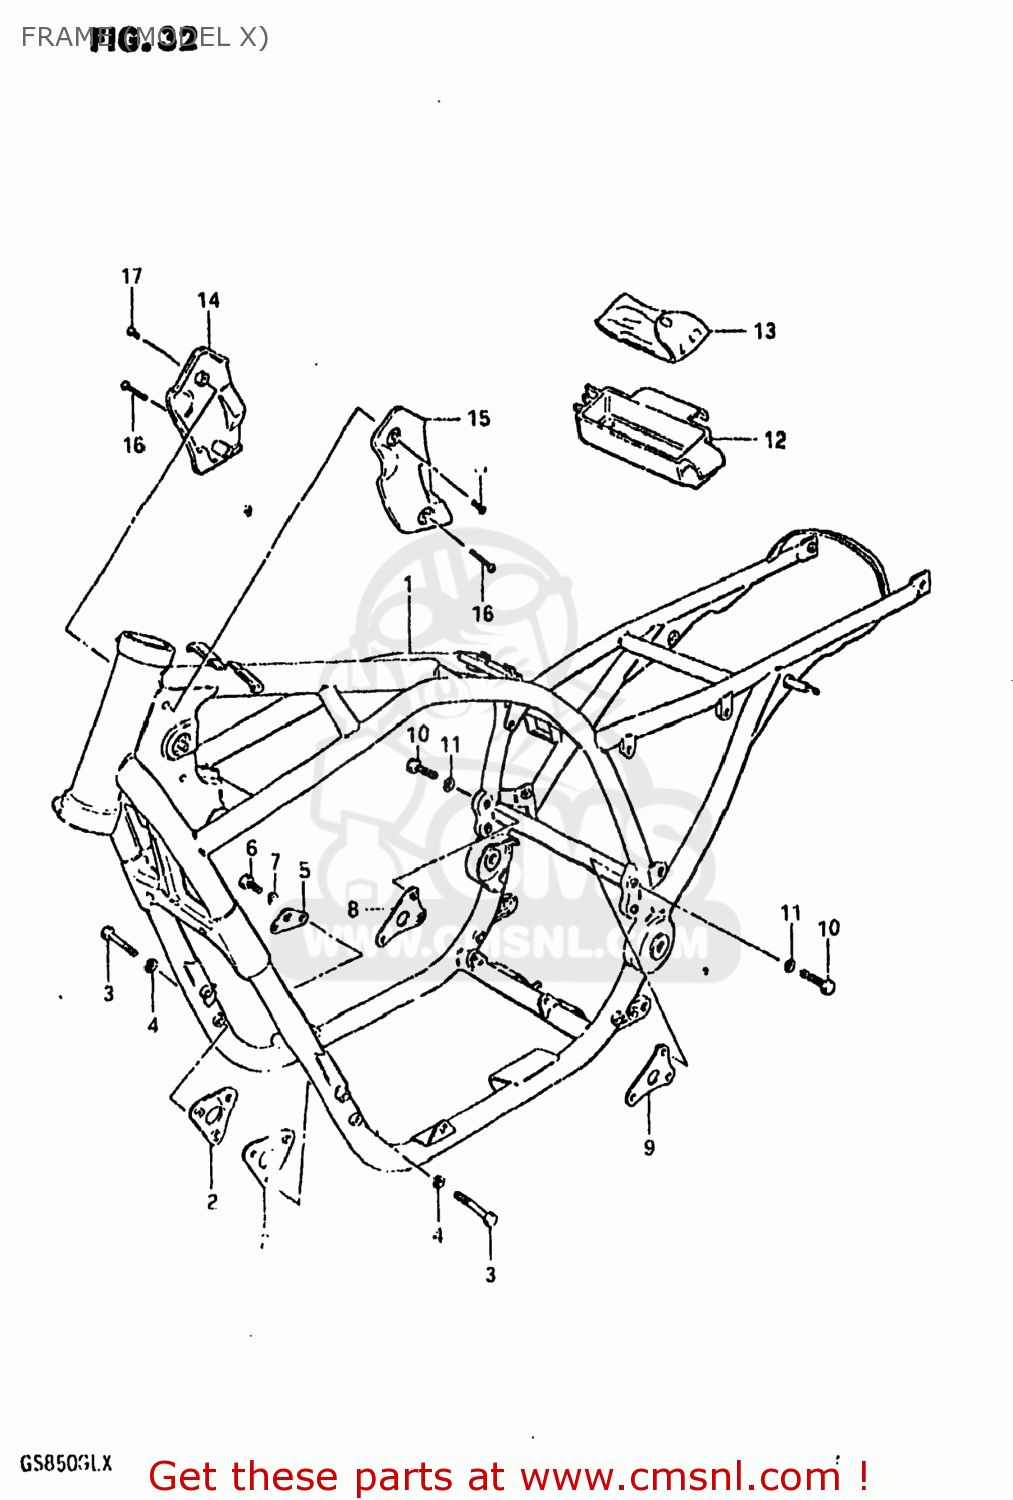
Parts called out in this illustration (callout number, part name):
1	FRAME
2	PLATE,ENGINE MOUNTING
3	BOLT
4	LOCK WASHER
5	PLATE,ENGINE MOUNTING
6	BOLT
7	LOCK WASHER
8	PLATE,ENGINE MOUNTING
9	PLATE,ENGINE MOUNTING
10	BOLT 8X40
11	LOCK WASHER
12	HOLDER,TOOL
13	TOOL SET
14	COVER,FRAME HEAD,RIGHT
15	COVER,FRAME HEAD,LEFT
16	SCREW, LOWER
17	SCREW
